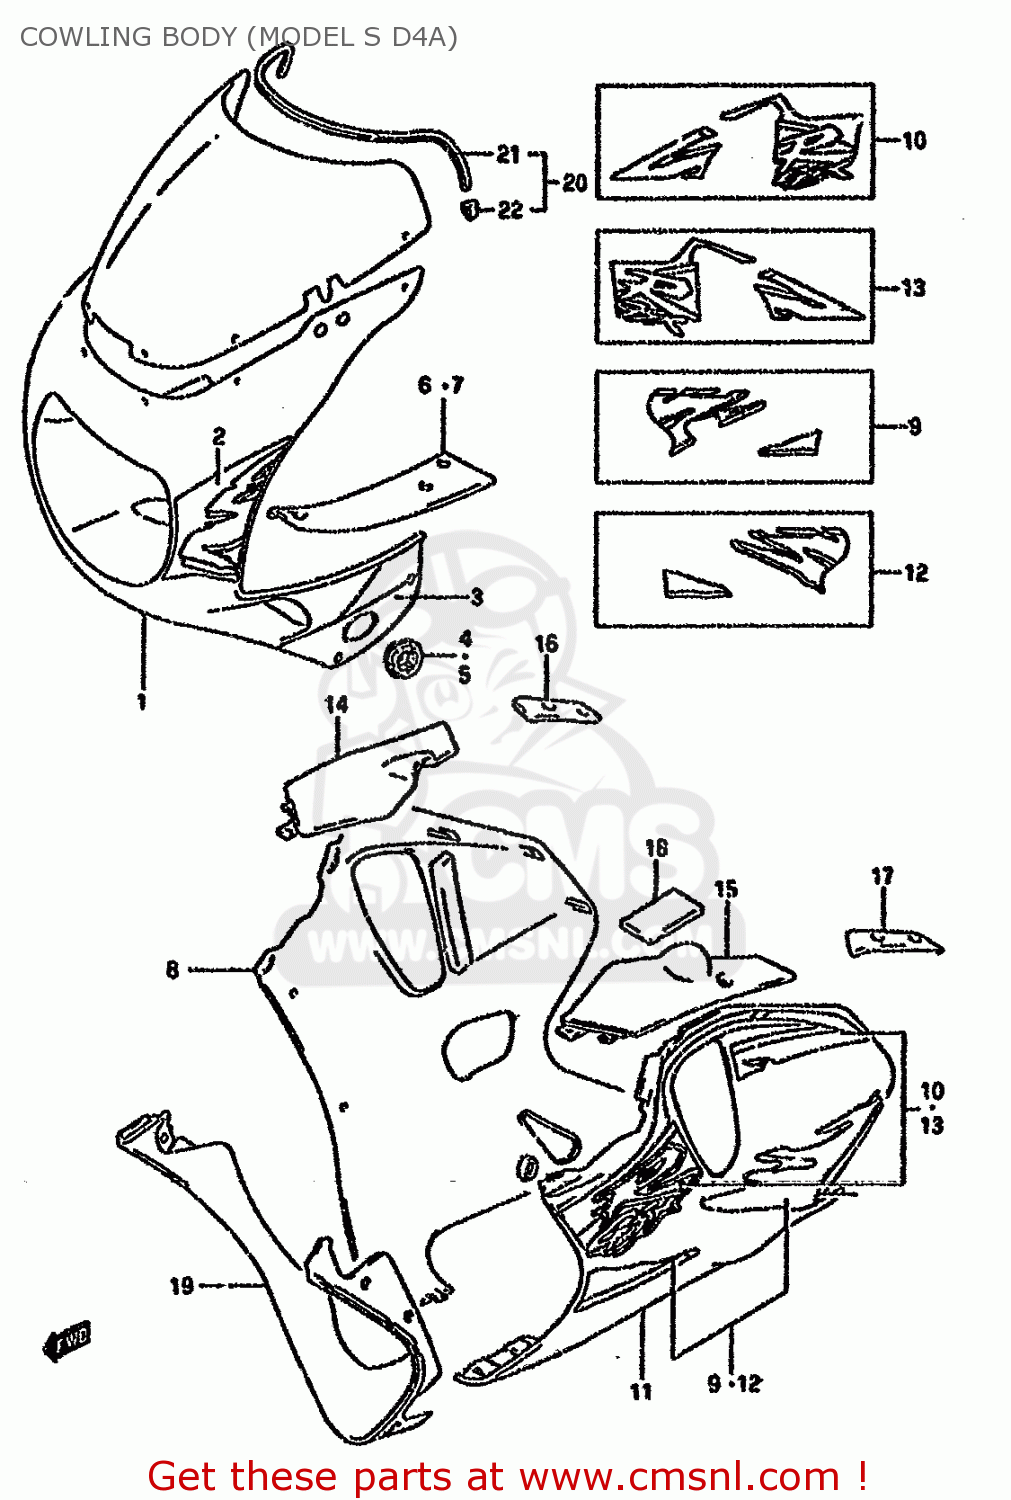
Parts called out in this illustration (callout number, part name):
1	COWLING ASSY,BODY (BLACK)
2	TAPE SET,COWL BODY FR
3	TAPE SET,COWL BODY SIDE
4	PLATE,TURN SIGNAL,RIGHT
5	PLATE,TURN SIGNAL,LEFT
6	PANEL,COWLING,UPPER,RIGHT
7	PANEL,UPPER,LEFT
8	COWLING ASSEMBLY,UNDER,RIGHT
9	TAPE SET,COWLING,UNDER,LOWER
10	TAPE SET,COWLING,UNDER
11	COWLING ASSEMBLY,UNDER,LEFT
12	TAPE SET,COWLING,UNDER,LOWER
13	TAPE SET,COWLING,UNDER
14	PANEL,LWR FR,R
15	PANEL,LWR FR,L
16	PANEL,LWR RR,R
17	PANEL,LWR RR,L
18	CUSHION,PANEL
19	COWLING,UNDER CTR
20	SCREEN SET,WINDOW
21	MOLDING WINDSCREEN
22	CLIP,WINDSCREEN MOLDING
